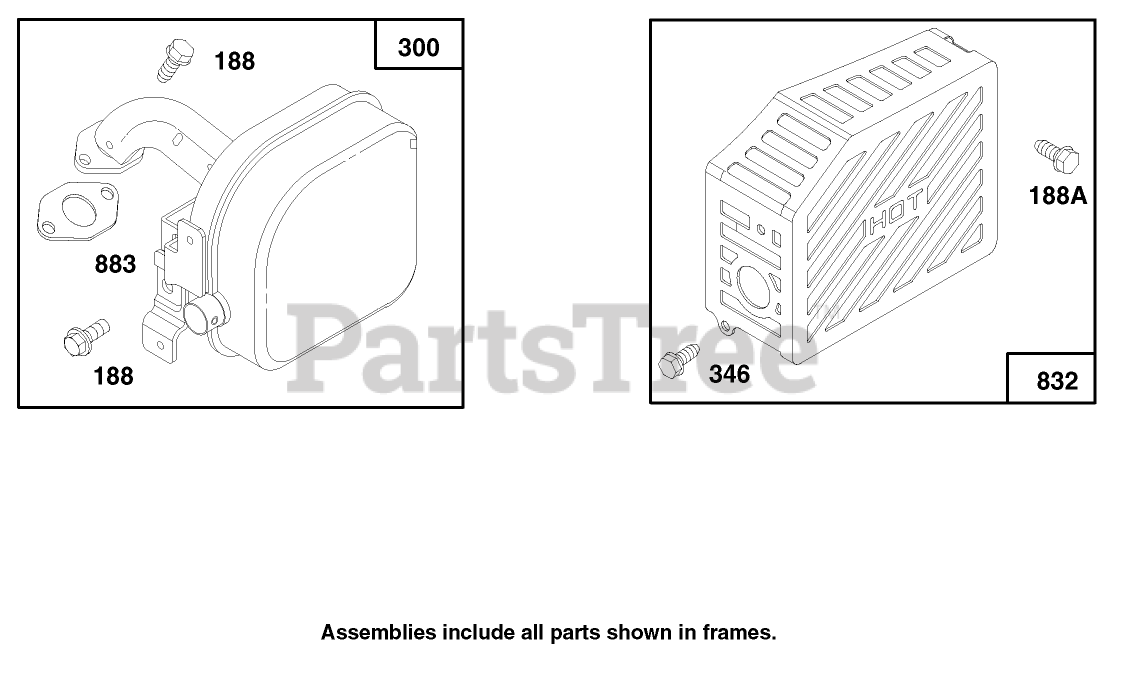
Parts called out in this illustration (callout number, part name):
188	SCREW - HEX HEAD
188A	SCREW - SEM
300	MUFFLER - EXHAUST
346	SCREW - SELF-TAPPING
